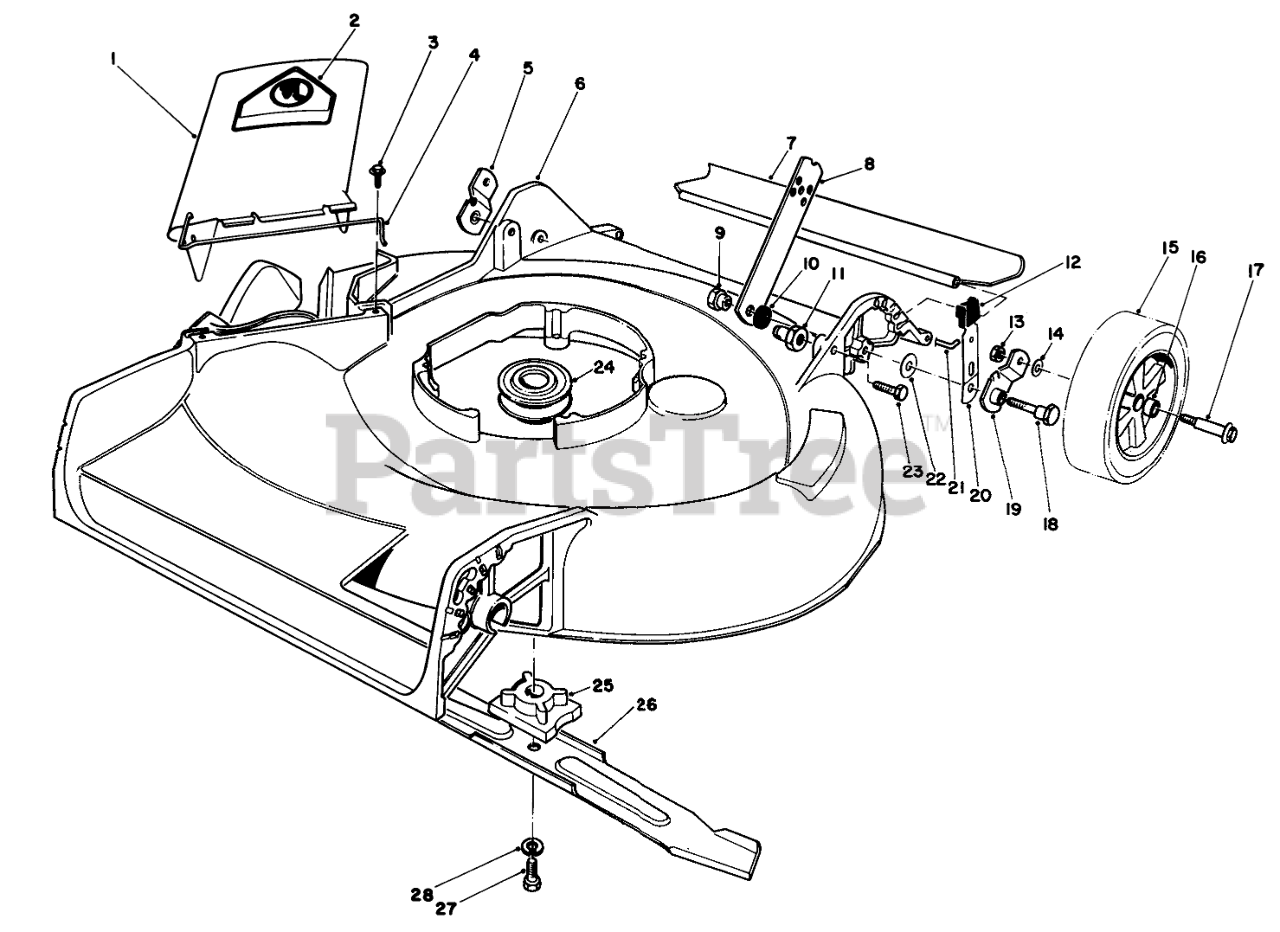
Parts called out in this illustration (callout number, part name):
1	Deflector Assembly (Incl.Ref. #2&4)
2	DECAL-DANGER
3	SCREW-HWH
4	SPRING HINGE
5	Pivot Arm
6	Housing
7	REAR SAFETY SHIELD 21
8	HANDLE LATCH
9	HANDLE PIVOT NUT
10	SPACER
11	HANDLE PIVOT NUT
12	KNOB-ARM
13	Nut
14	WASHER
15	Wheel 8 Tire Assembly (Incl. Ref. #16)
16	BUSHING
17	BOLT-WHEEL
18	PIVOT SCREW
19	Pivot Arm
20	SPRING ARM ASM
21	SHIELD ROD
22	WASHER-PIVOT
23	SCREW-HH
24	PULLEY-DRIVER
25	BLADE RETAINER
26	Blade
27	SCREW-HH
28	WASHER-LOCK
